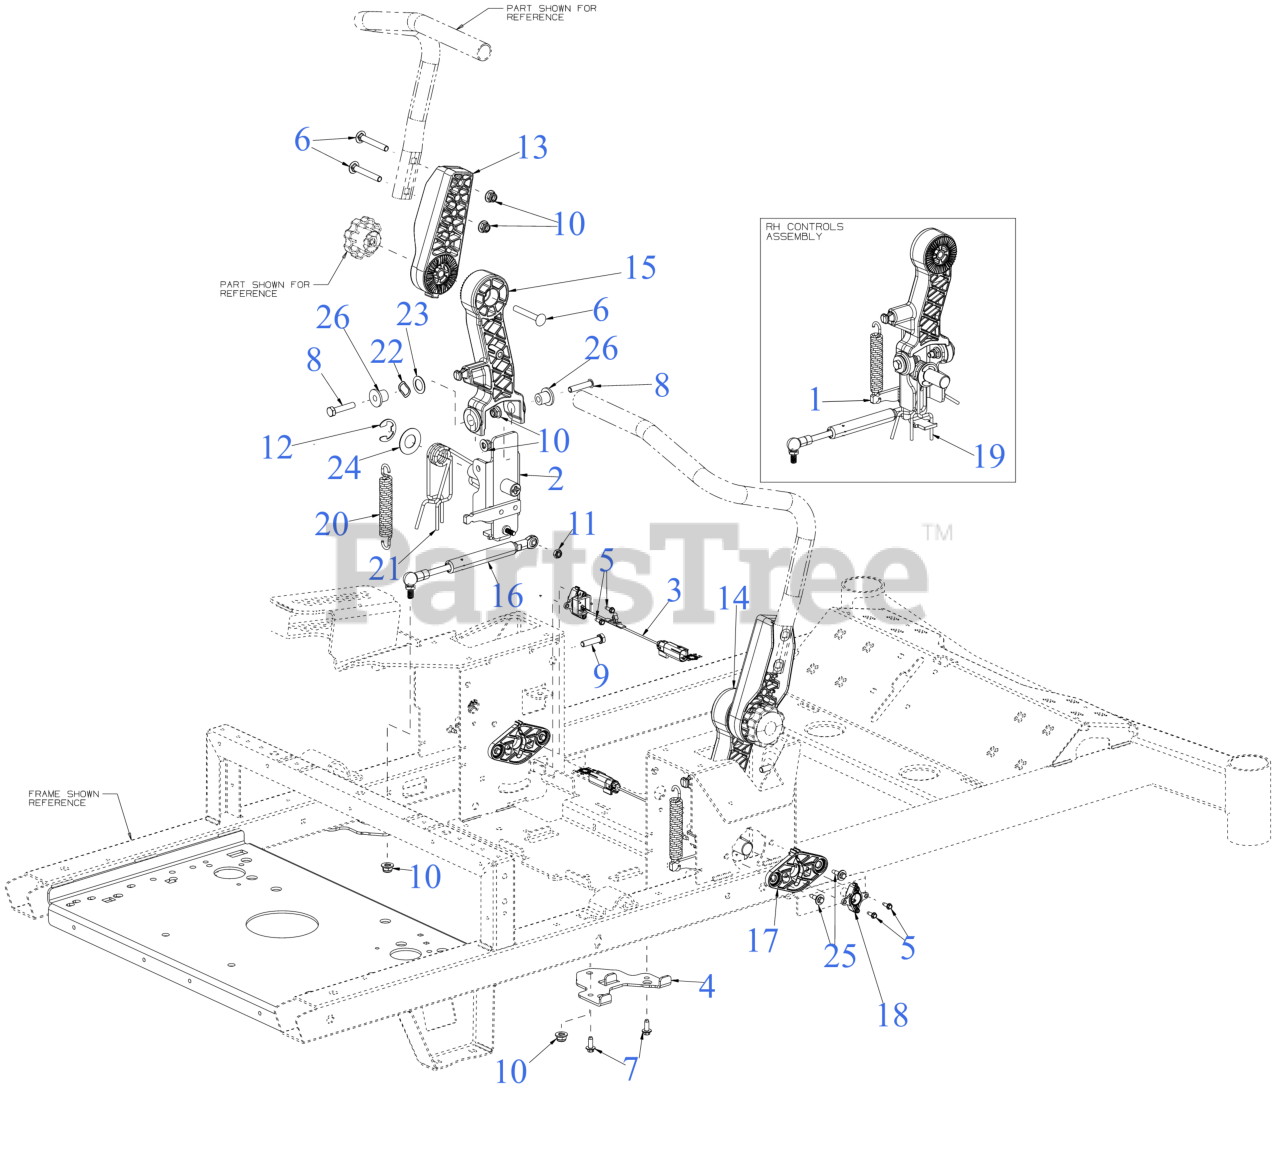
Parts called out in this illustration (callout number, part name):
1	CONTROL BRACKET (RH)
2	CONTROL BRACKET (LH)
3	THROTTLE SENSOR
4	DAMPNER BRACKET
5	SCREW #8-16 x .50
6	BOLT 5/16-18 x 2.50 GR1
7	SCREW M6-1 x .625
8	SCREW 5/16-18 x 1.5 LG
9	SCREW 5/16-18 x 1.25 GR5
10	FLANGE LOCK NUT 5/16-18
11	HEX NUT 1/4-20
12	RETAINING RING
13	UPPER ADJUSTMENT HANDLE
14	LAPBAR ACTUATOR (RH)
15	LAPBAR ACTUATOR (LH)
16	DAMPER- .71 OD X 9.48 LG ERZT
17	CONTROL HOUSING
18	Mount
19	TORSION SPRING 0.860 ID (RH)
20	EXTENSION SPRING .700 ODx4.800
21	TORSION SPRING 0.860 ID (LH)
22	WAVE WASHER .660 ID X.88 OD x .010
23	FLAT WASHER
24	THRUST WASHER
25	SHOULDER SCREW M6-1 .368 X.115
26	SHOULDER SPACER .32 x .625 x .66
